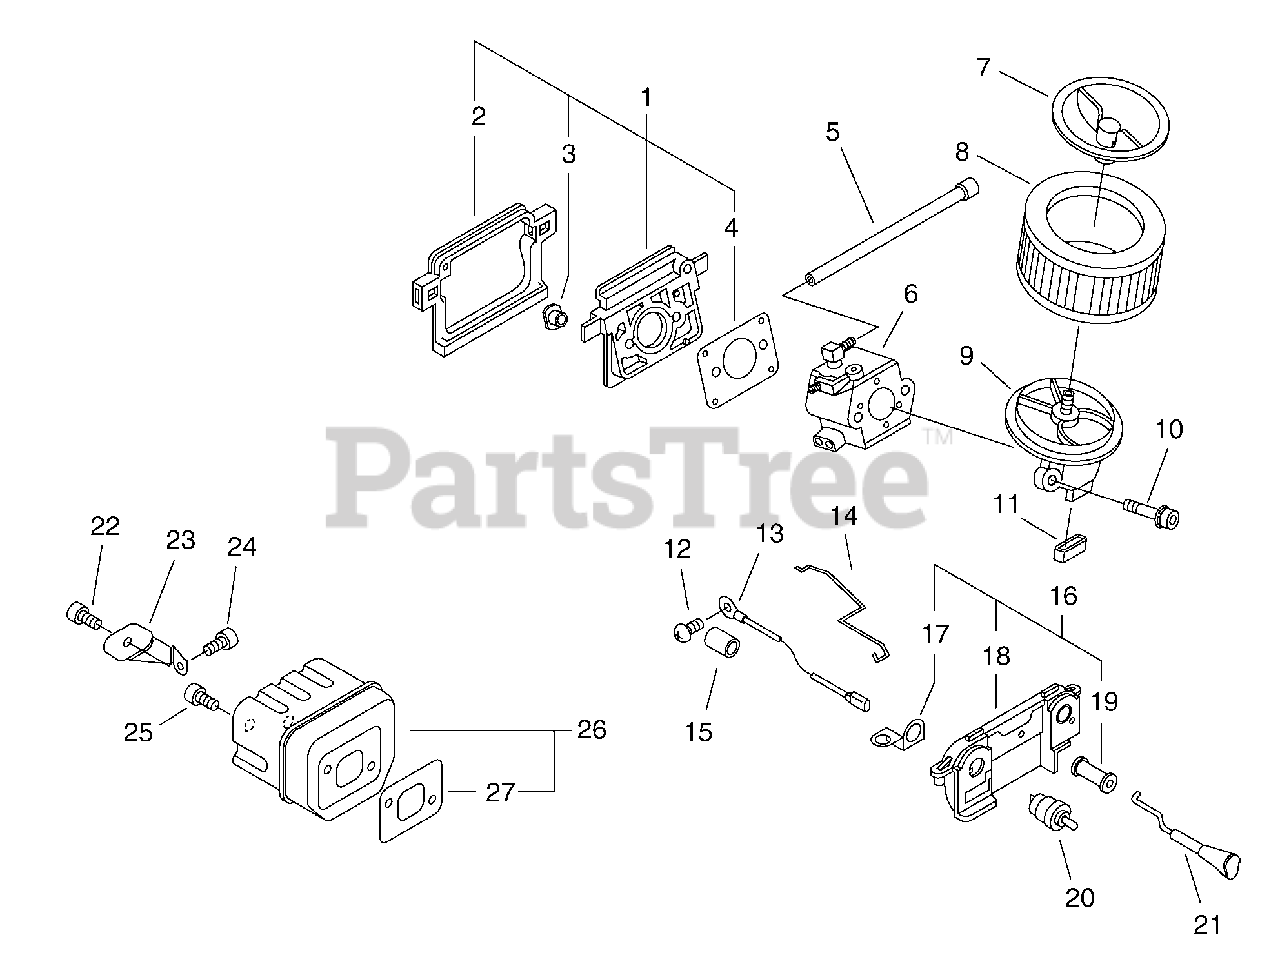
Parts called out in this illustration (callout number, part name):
1	INSULATOR KIT, INTAKE
2	CUSHION
4	GASKET, INTAKE
5	PIPE, IMPULSE 3×5×110
6	CARBURETOR
7	CAP, AIR FILTER
8	FILTER, AIR
9	MOUNT, AIR FILTER
10	BOLT 5×50
12	SCREW 4×6
13	LEAD #250-210-LA104
14	ROD, THROTTLE
15	BOOT, CONNECTOR
16	BRACKET, SWITCH
17	TERMINAL, SWITCH
18	BRACKET, SWITCH
19	GROMMET, CHOKE
20	SWITCH, ON-OFF
21	ROD, CHOKE
22	BOLT 6×8
23	BRACKET, MUFFLER
24	SCREW 6×14
25	BOLT 5×14
26	MUFFLER ASSY
27	GASKET, MUFFLER
